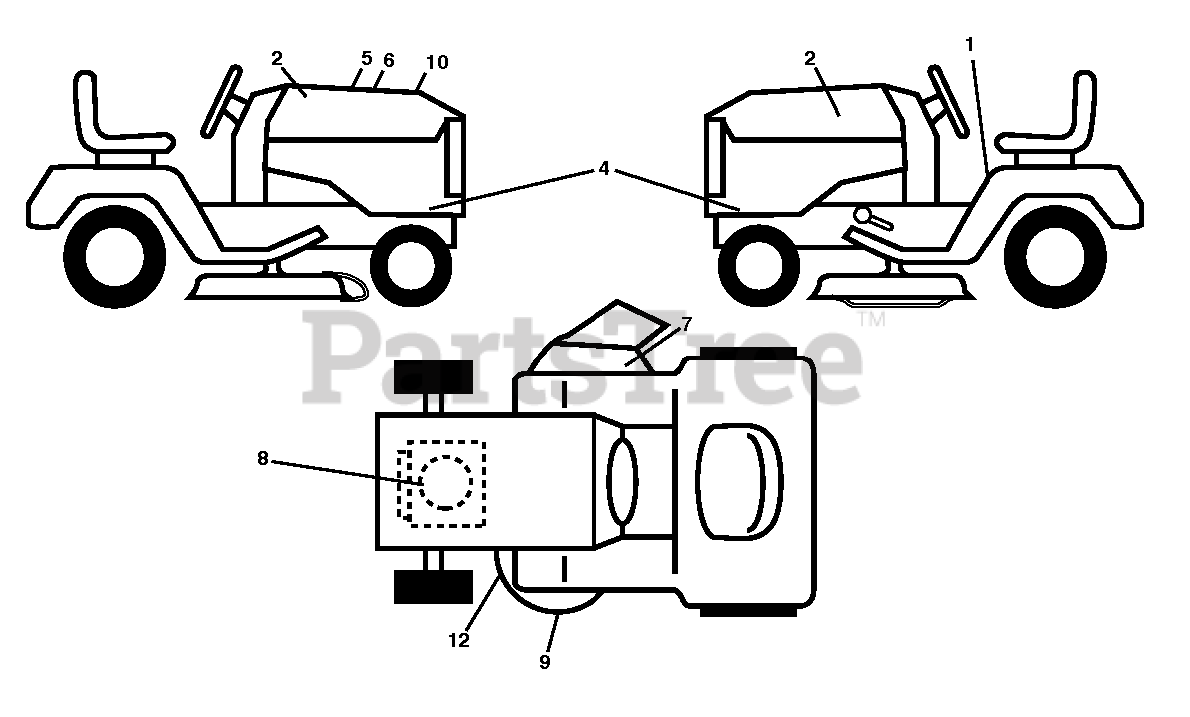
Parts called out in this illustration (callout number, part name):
1	DECAL.WARN.STARTINST.LOWEARIEN
2	DECAL.BADGE.170MM.TEXTLOGO.
4	DECAL SIDEPANEL
5	DECAL.WARNING.CUST.RESP.E85.
6	DECAL.RPL.BSM33.INTK.TLW
7	DECAL, DECK DEFLECTOR, WARNING
8	DECAL.ENG.BS.18.5INTK.381713
10	DECAL.E85.WARNING.2012
12	DECAL.V-BELT.SCH.42/46"MEC/ELE
